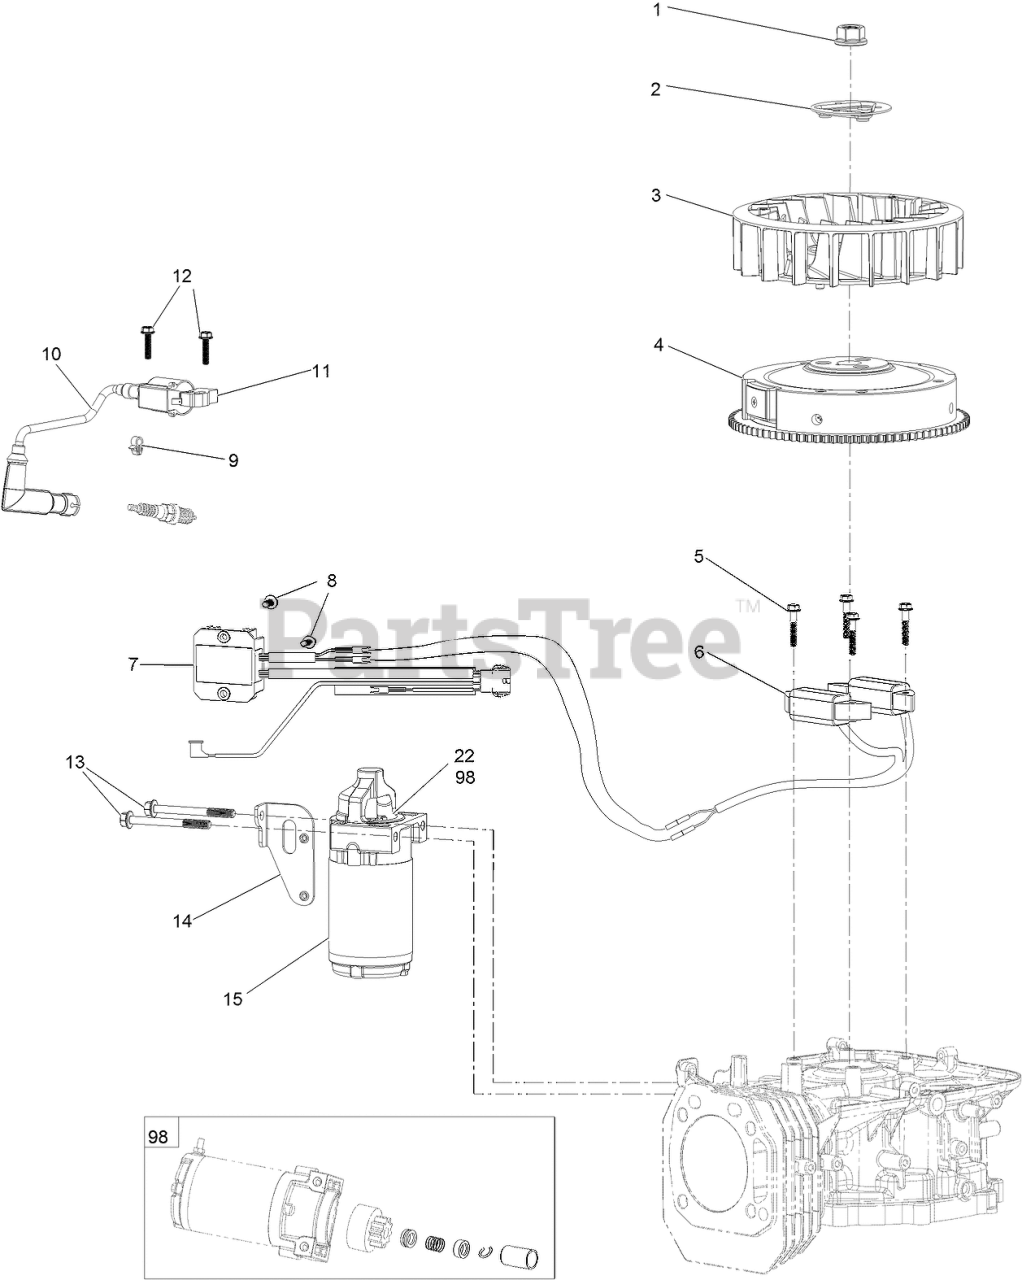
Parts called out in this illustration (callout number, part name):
1	NUT-FLANGE
2	PULLEY-STARTER
3	FAN-COOLING
4	FLYWHEEL
5	SCREW-HHF
6	ALTERNATOR
7	VOLTAGE REGULATOR
8	SCREW-HHF
9	CLAMP-WIRE
10	BOOT-PLUG, SPARK
11	IGNITION COIL ASM
12	SCREW-HHF
13	SCREW-HHF
14	BRACKET-STARTER
15	MOTOR-STARTER
22	PINION-STARTER
98	STARTER REPAIR KIT
